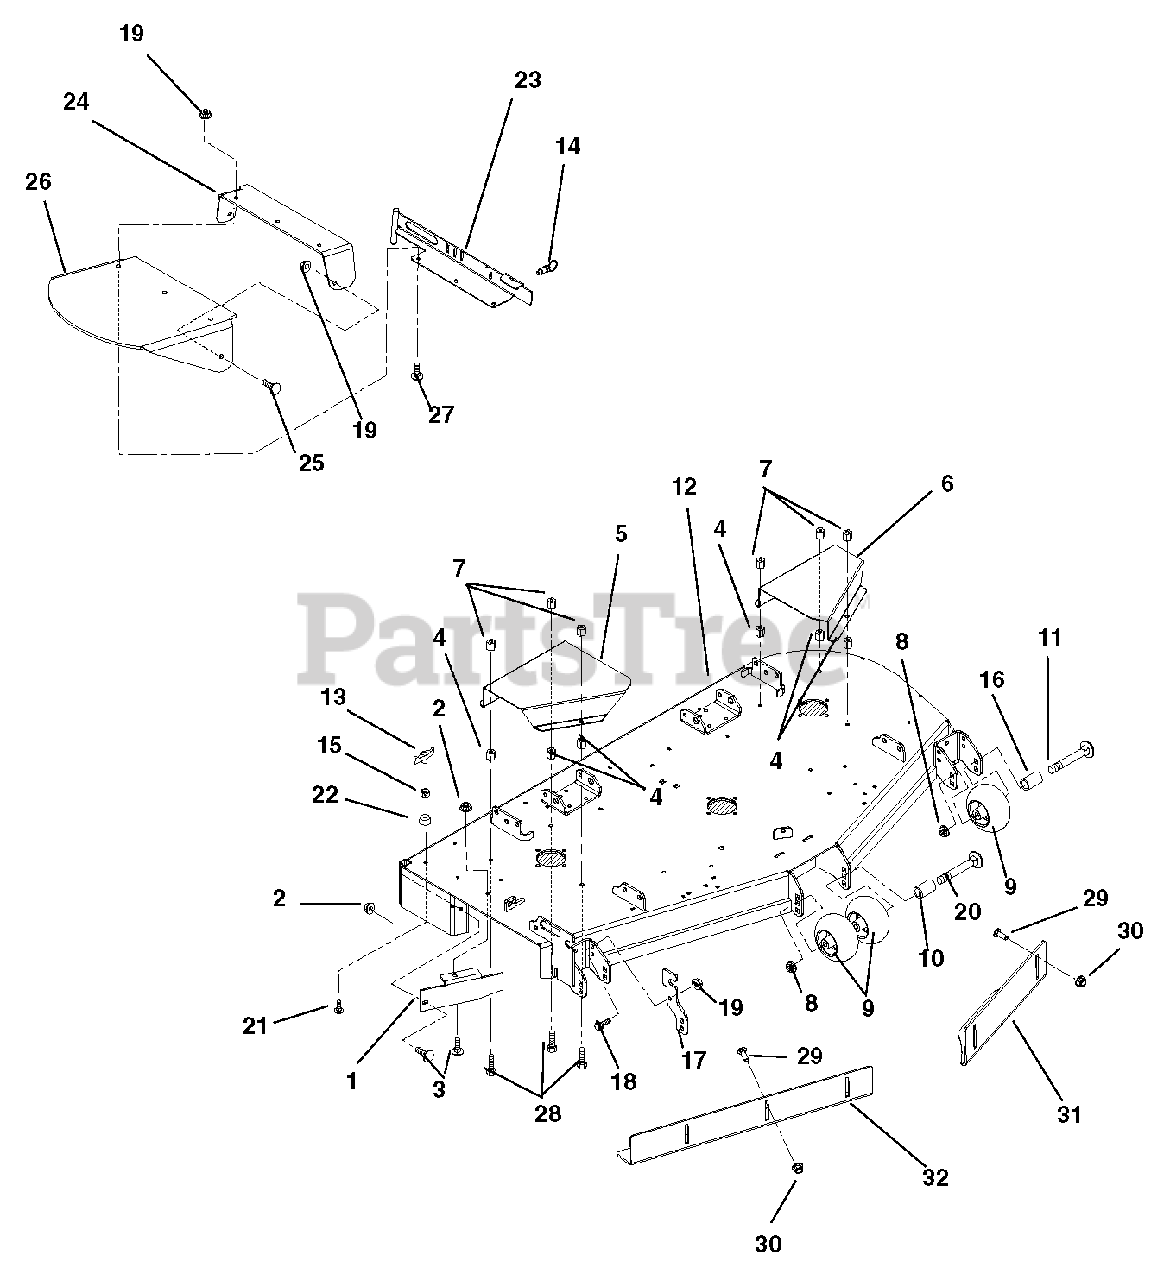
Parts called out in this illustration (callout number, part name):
1	60" Discharge Baffle
2	Nut, .31-18 Nyloc Flange
3	Bolt, Round Head Square Neck .31-18 x 1.00 Grade 5
4	Nut, Heavy Hex .38-16
5	Belt Guard, 60" Right Hand Deck
6	Belt Guard, 60" Left Hand Deck Belt Guard
7	Nut, Spin Lock-Flange .375-16
8	Nut, .50-13 Nyloc Flange
9	Wheel, Anti-Scalp 5 x 3
11	Bolt, Round Head Square Neck .50-13X5.00
12	Deck, 60" Side Discharge Mower
13	Knob, Clamping .312-18
14	Pin, Plunger Pull .50-13 Thread x .310 Diameter
15	Nut, Locking, Center .31-18
16	Spacer, .510 x .625 x 3.35
17	Chute, Storage Bracket
18	Bolt, Hex .38-16 x 1.00
19	Nut, Nyloc Flange .38-16
20	Bolt, Round Head Square Neck .50-13 x 8.50
21	Bolt, Round Head Square Neck .31-18 x 1.50
22	Bumper, Recessed 1.50 x .63, .31 Thru Hole
23	60" Discharge Chute Mounting Weldment
24	Rubber Discharge Chute Support
25	Bolt, Round Head Square Neck .38-16 x 1.00 Grade 5
26	Chute, Rubber Discharge
27	Bolt, Round Head Square Neck .38-16 x 1.25 Grade 5
28	Bolt, Hex .38-16 x 1.25 Grade 5
29	Bolt, Round Head Square Neck .31-18 x .75 Grade 5
30	Nut, Nyloc .312-18 YWZC
31	Baffle, 60" Left Hand Vacuum
32	Baffle, 60" Right Hand Vacuum
